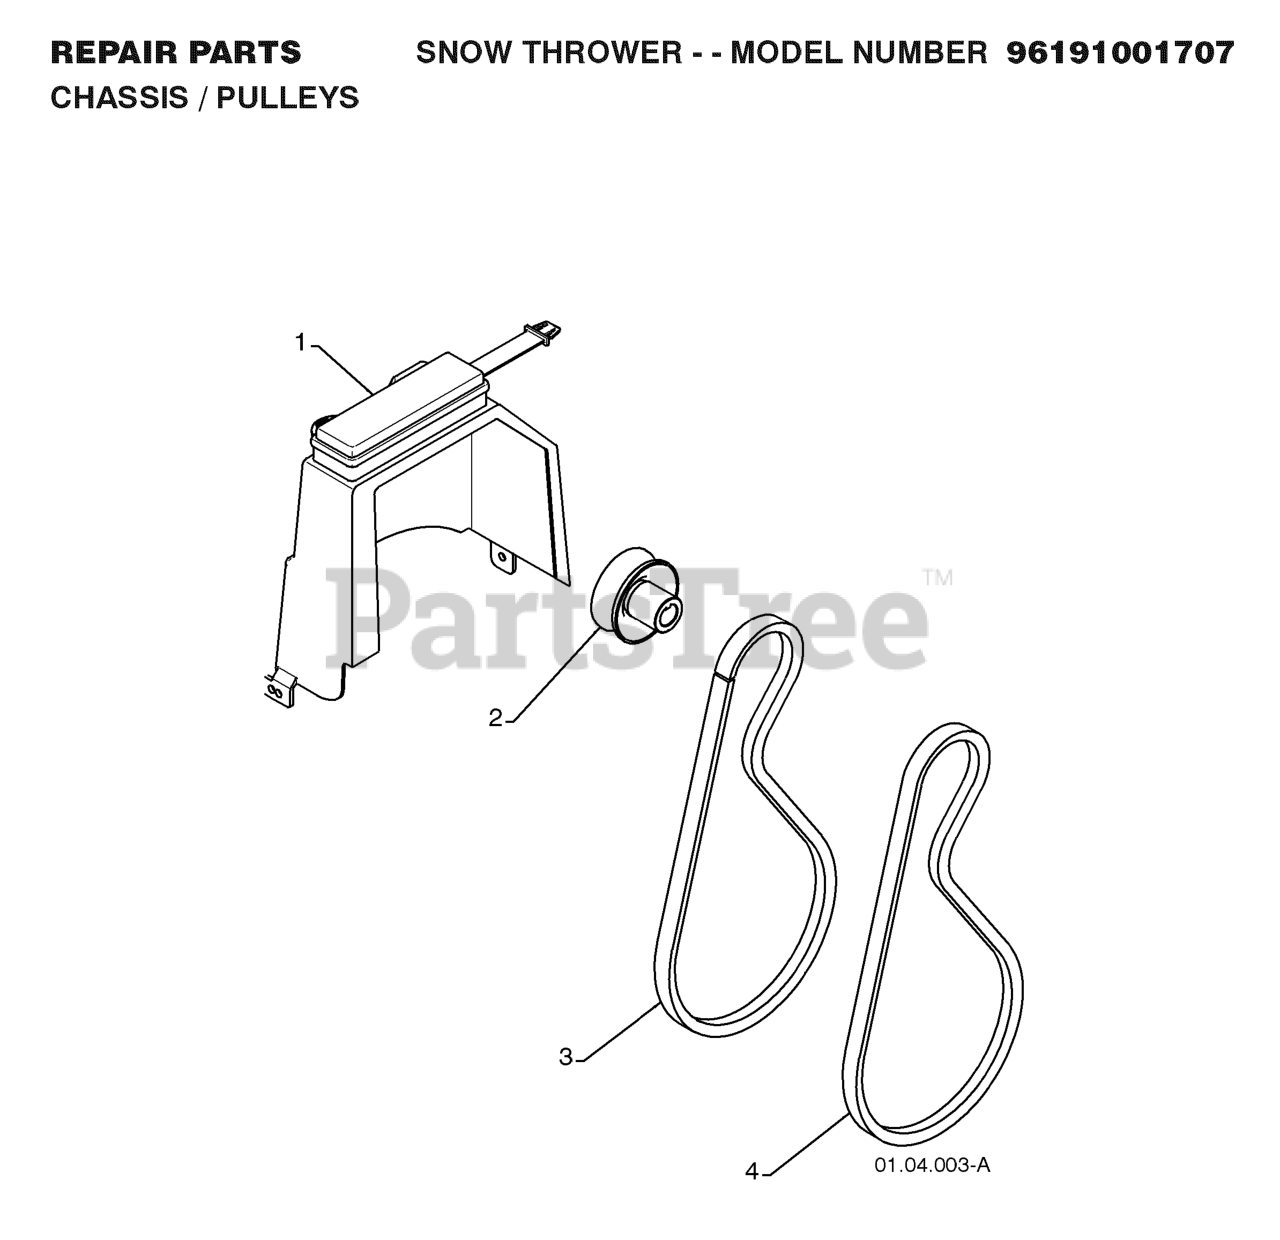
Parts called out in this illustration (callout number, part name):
1	COVER.ASM.BELT/STORAGE
2	PULLEY, ENGINE IMPELLER DRIVE
3	V-BELT TRACTION 34.25
4	BELT.V.IMPELLER
